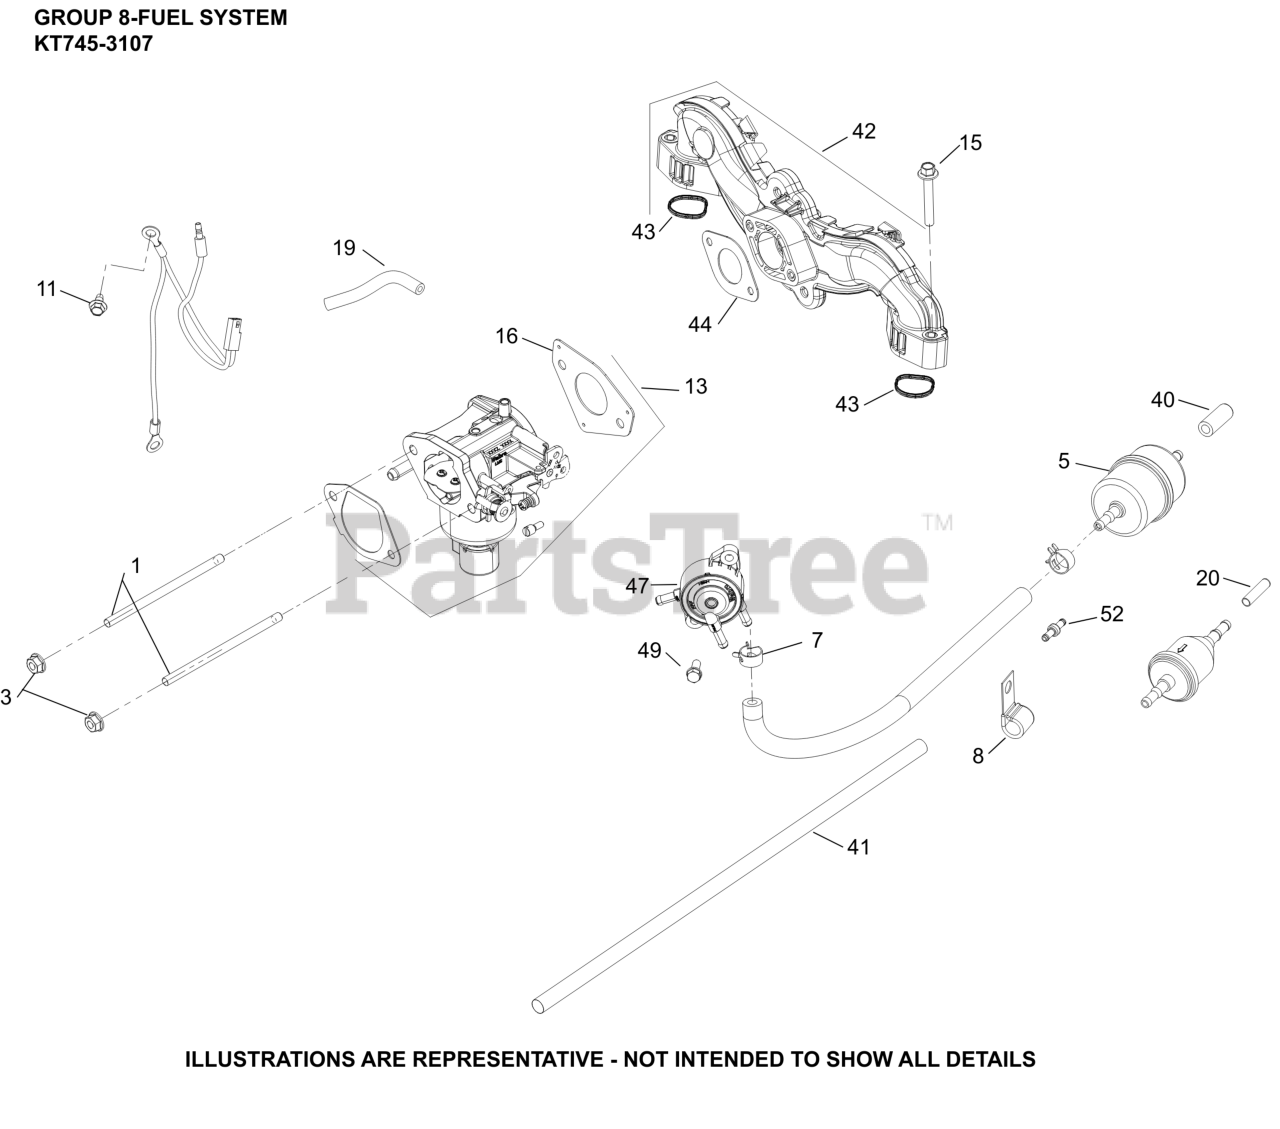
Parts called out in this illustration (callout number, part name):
3	NUT, FLG M6X1.0
5	FILTER, FUEL
7	SPRING CLAMP, HOSE
8	CLIP, CABLE (KM)
11	SCREW, THREAD FORMING
13	KIT,CARB(WALBRO)
15	SCREW, FLG M6X1.0X40
16	GASKET, CARBURETOR-(#2404191S)
19	HOSE, EVAPORATIVE 20"- (#24326143S)
20	CAP, MASKING
40	MASKING CAP
41	SLEEVE, ANTI-ABRASION
42	INTAKE MANIFOLD W/GASKETS
43	O-RING, INTAKE PORT
44	GASKET, CARBURETOR (PIM, CV)
47	PUMP, FUEL (PULSE)
49	SCREW, HEX HEAD
52	FITTING, FUEL SYSTEM
NI	KIT,REPAIR OVERHAUL(WALBRO)
NI	KIT,BOWL O-RING(WALBRO)
NI	KIT, HIGH ALT (4000-8000 FT)(WALBRO)
NI	KIT,SOLENOID REPAIR(WALBRO)
NI	KIT,REPAIR FLOAT(WALBRO)
